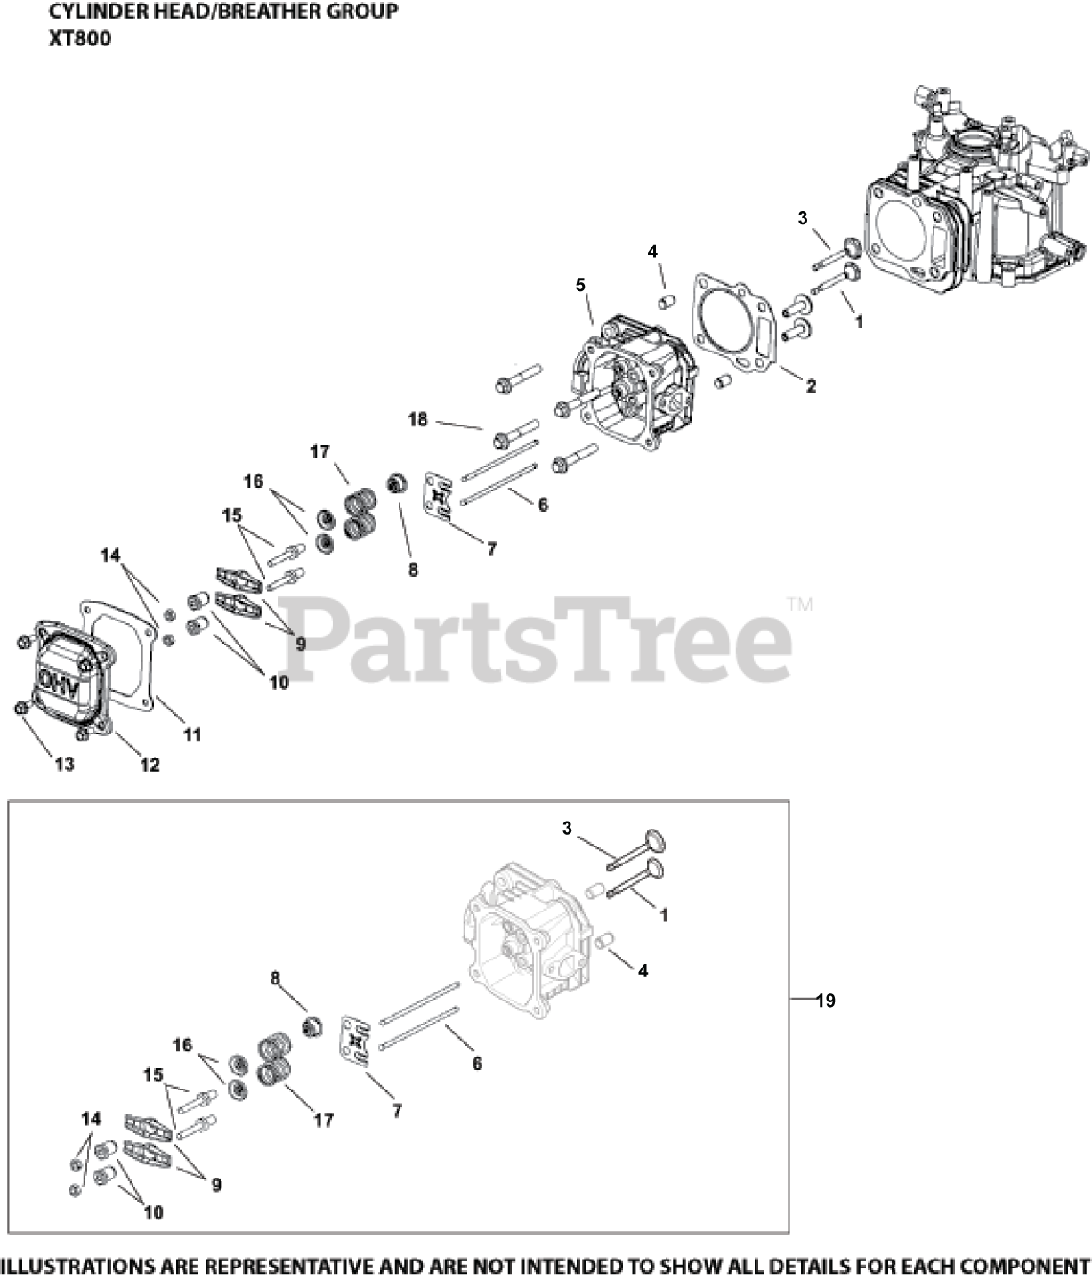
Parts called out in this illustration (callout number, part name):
1	VALVE, EXHAUST
2	KIT, HEAD GASKET USE 14 841 34-S
3	VALVE, INTAKE
4	DOWEL, CYLINDER HEAD-(#1438013S)
5	HEAD, CYLINDER USE 14 318 10-S
6	ROD, PUSH
7	PLATE, PUSHROD GUIDE
8	SEAL, VALVE STEM
9	ARM, ROCKER
10	PIVOT, ROCKER ARM
11	GASKET, VALVE COVER
12	COVER, VALVE
13	SCREW, HEX FLANGE (M6)-USE 25 086 433-S
14	NUT, HEX JAM
15	STUD, ROCKER ARM
16	RETAINER, VALVE SPRING
17	SPRING, VALVE
18	SCREW, HEX FLANGE M8
19	KIT, VALVE TRAIN
